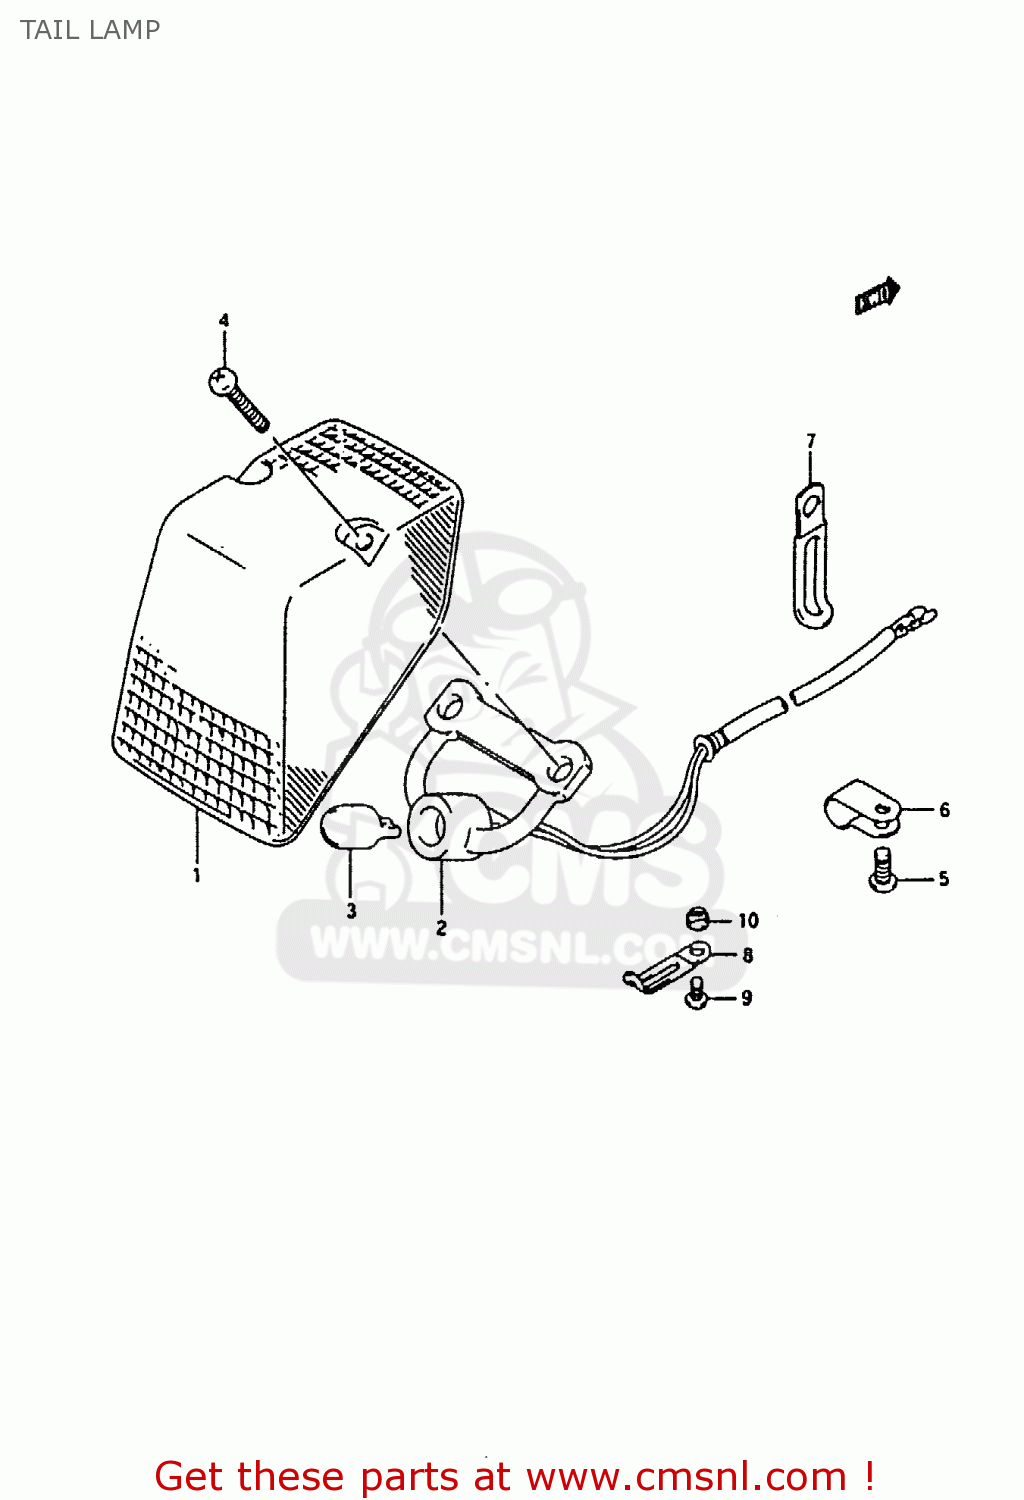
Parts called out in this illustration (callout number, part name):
1	LENS
2	SOCKET & CORD,RR COMBINATION
3	BULB
4	SCREW
5	SCREW
6	CLAMP
7	CLAMP
8	CLAMP(L:45)
9	SCREW
10	NUT
